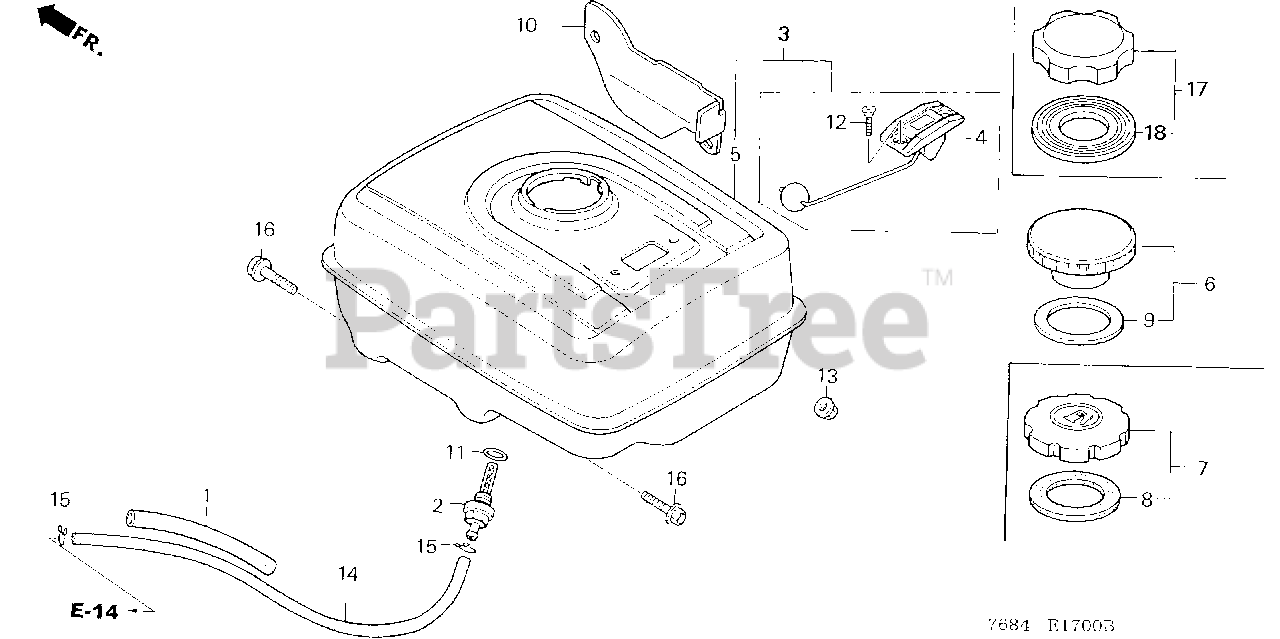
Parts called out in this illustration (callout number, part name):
1	RUBBER, SUPPORTER (107MM)
2	JOINT, FUEL TANK
3	TANK ASSY., FUEL *R280* (GAUGE) (POWER RED)
4	GAUGE ASSY., FUEL
7	CAP, FUEL FILLER (BLACK)
8	GASKET, FUEL FILLER CAP (39X58X3)
10	COVER, SNOW PLATE
11	O-RING (13.5X1.5) (ARAI)
11	O-RING (14MM) (NOK)
12	SCREW, FLAT (5X10)
13	NUT, FLANGE (8MM)
14	BULK HOSE, FUEL (4.5X3000) (4.5X222)
15	CLIP, TUBE (B8)
16	BOLT, FLANGE (8X25)
17	CAP, FUEL FILLER (CHROME PLATED)
18	GASKET, FUEL FILLER CAP (39X62X3) (TOUYOUSYA)
